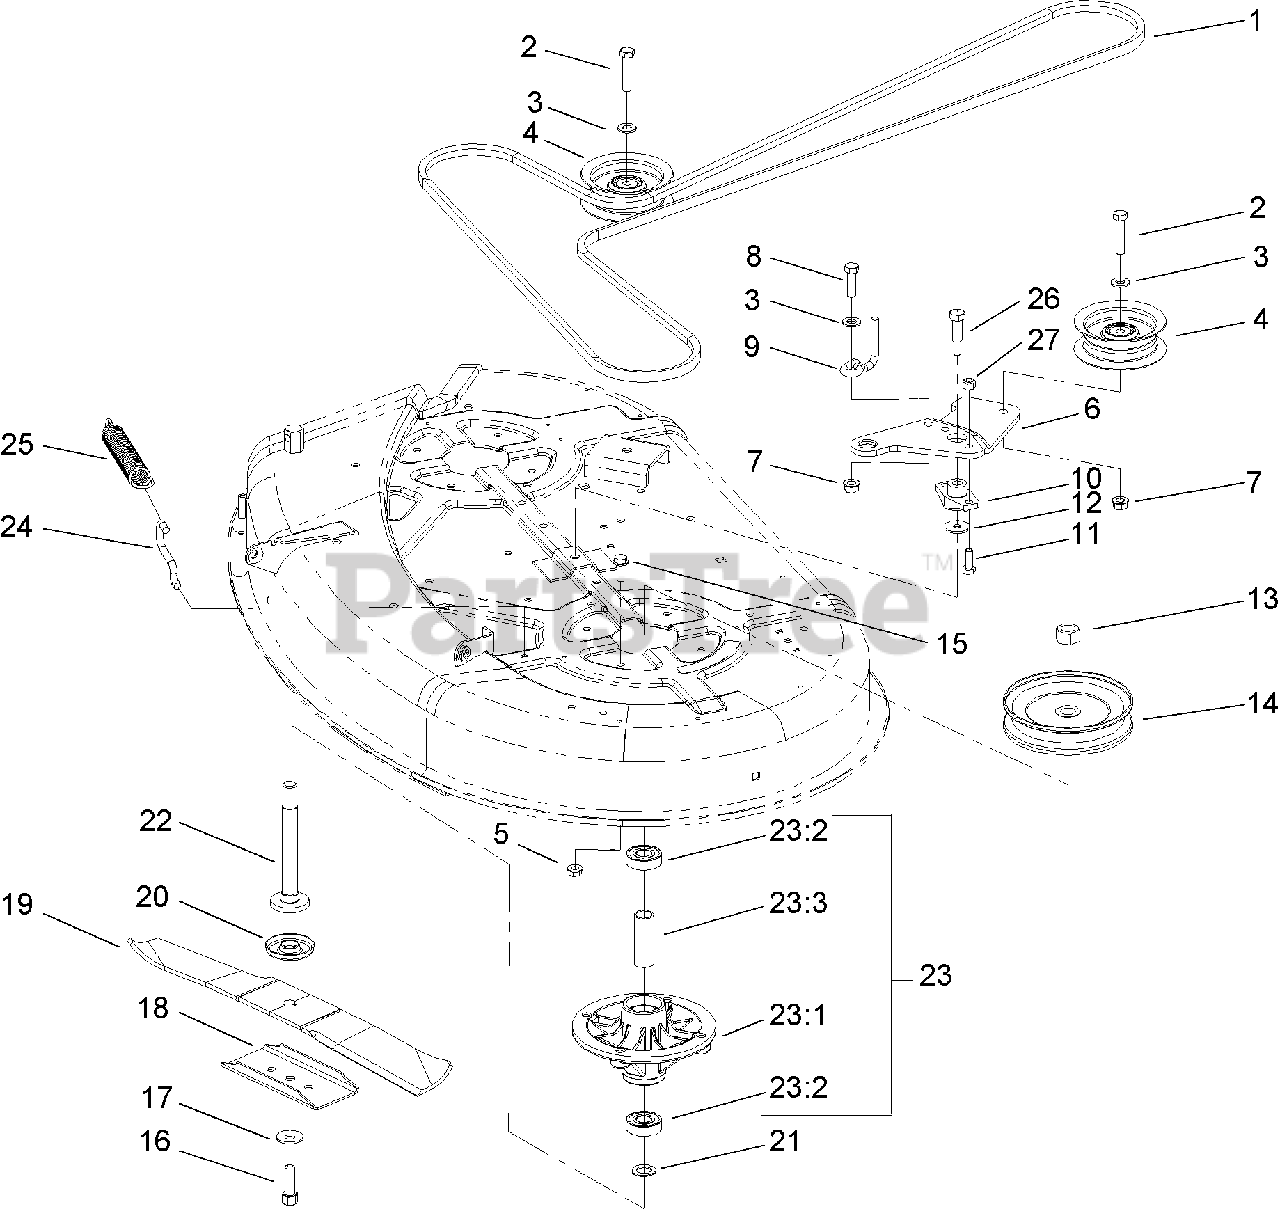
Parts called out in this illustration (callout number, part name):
2	SCREW-HH
3	WASHER-FLAT
4	PULLEY-IDLER, FLAT
8	SCREW-HH
9	GUIDE-IDLER, BELT
10	BUSHING-ARM, IDLER
11	SCREW-HH
12	WASHER-PIVOT
13	NUT-HEX
14	PULLY-DECK
15	SCREW-TAPTITE
16	SCREW-BLADE
17	WASHER-BELLEVILLE
18	STIFFENER-BLADE
20	SHIELD-BEARING
22	SHAFT-SPINDLE
23	Spindle ASM
23:1	HOUSING-SPINDLE
23:2	BEARING-BALL
23:3	SPACER-BEARING
24	HOOK-RETURN, SPRING
25	SPRING-EXTENSION
26	BOLT-SHOULDER
27	NUT-LOCK, NI
